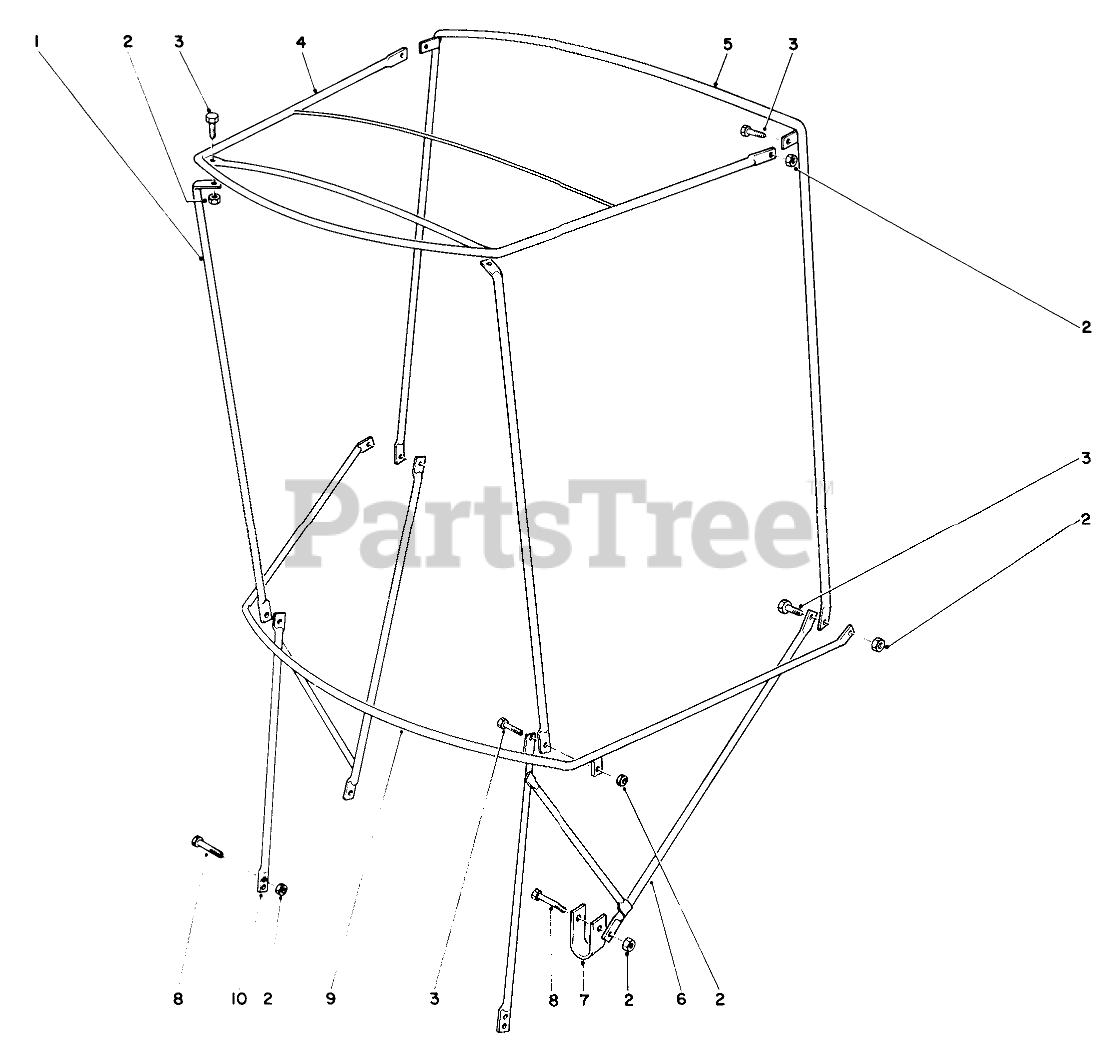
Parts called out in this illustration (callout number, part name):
2	NUT-HEX, SIDE DEFORM
3	SCREW-HH
4	FRAME-TOP
5	BOW-VERTICAL, REAR
6	ATTACHING BRKT L
7	U CLAMP
8	SCREW-HH
9	BOW-CURVED
10	Attaching Bracket R.H.
